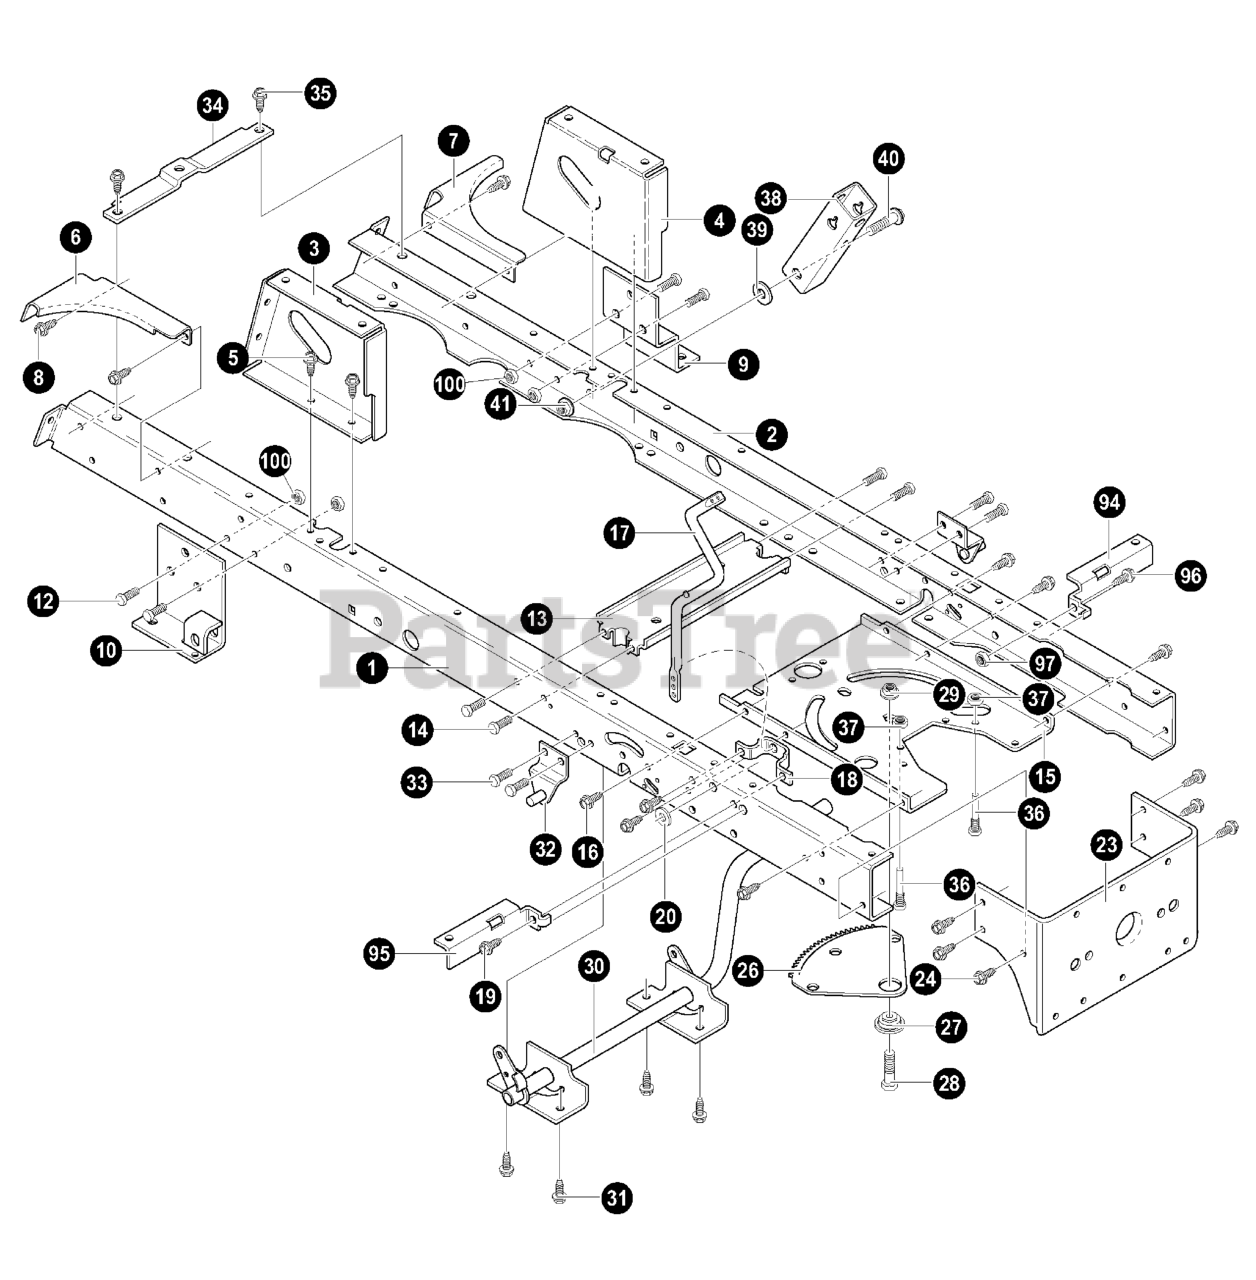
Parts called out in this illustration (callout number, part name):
1	FRAME, RAIL RH
2	FRAME, RAIL LH
3	SUPPORT, SEAT RH
4	SUPPORT, SEAT LH
5	SCREW 5/16-18X.75 HHWATAP
6	BRACE, BACKPLATE RH
7	BRACE, BACKPLATE LH
8	SCREW 5/16-18X.75 HHWATAP
9	BRACKET, T/A RH VST, LH-MST
10	ASSY., SHIFT BRACE
12	SCREW, 5/16-18 x 0.75 HHWATAP
13	ASM. IDLER MOUNT, FRONT
14	SCREW, 5/16-18 x 0.75 HHWATAP
15	PLATE, STEERING
16	SCREW, 5/16-18 x 0.75 HHWATAP
17	CRANK, PTO
18	BRACKET, BELL CRANK
19	SCREW, 5/16-18 x 0.75 HHWATAP
20	WASHER, FLAT .469X.92X.065
23	BRACKET, HANGER REAR
24	SCREW, 5/16-18 x .75 HHWATAP
26	GEAR, SECTOR
27	BEARING, SECTOR GEAR
28	SCREW, 5/16-18 x 1.00
29	NUT, 5/16-18 HEXKEPS 15X113
30	CLUTCH/BRAKE PEDAL
31	SCREW, 5/16-18 x 0.75 HHWATAP
32	BRACKET, SUSPENSION ASM.
33	SCREW, 5/16-18 x 0.75 HHWATAP
34	BRACE, RAIL
35	SCREW, 5/16-18 x 0.75 HHWATAP
36	ZINC SCREW GUIDE
37	NUT, 5/16-18 HEXWDFLLK WHIZ
38	BRACKET, PIVOT
39	WASHER, FLAT .390X1.25X.119
40	BOLT, .562X1.563 HHSH 3/8-16
41	NUT, 3/8-16 HWDFLLK MACK 15X84
94	BRACKET, SEAT DECK LH
95	BRACKET, SEAT DECK RH
96	SCREW, 5/16-18 x 0.75 HHWATAP
97	NUT, 5/16-18 HEXWDFLLK WHIZ
100	NUT, 5/16-18 WDFLLK
